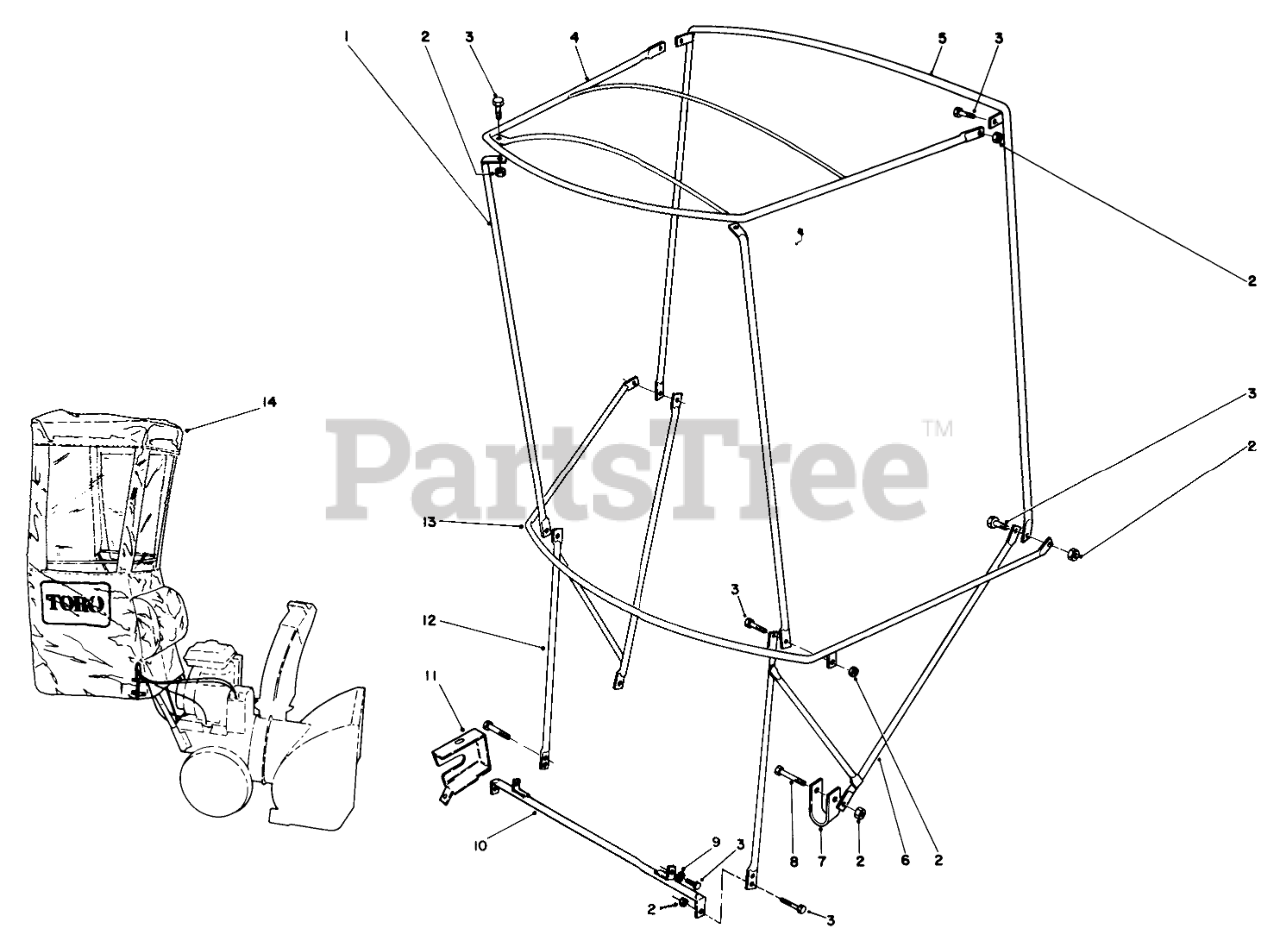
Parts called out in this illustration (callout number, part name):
2	NUT-HEX, SIDE DEFORM
3	SCREW-HH
4	FRAME-TOP
5	BOW-VERTICAL, REAR
6	Bracket-LH
7	CLAMP
8	SCREW-HH
9	WASHER-FLAT
10	Bracket-Base
11	COVER-LOCK, LEVER
12	BRACKET-RH
13	BOW-CURVED
14	Cover-Vinyl
